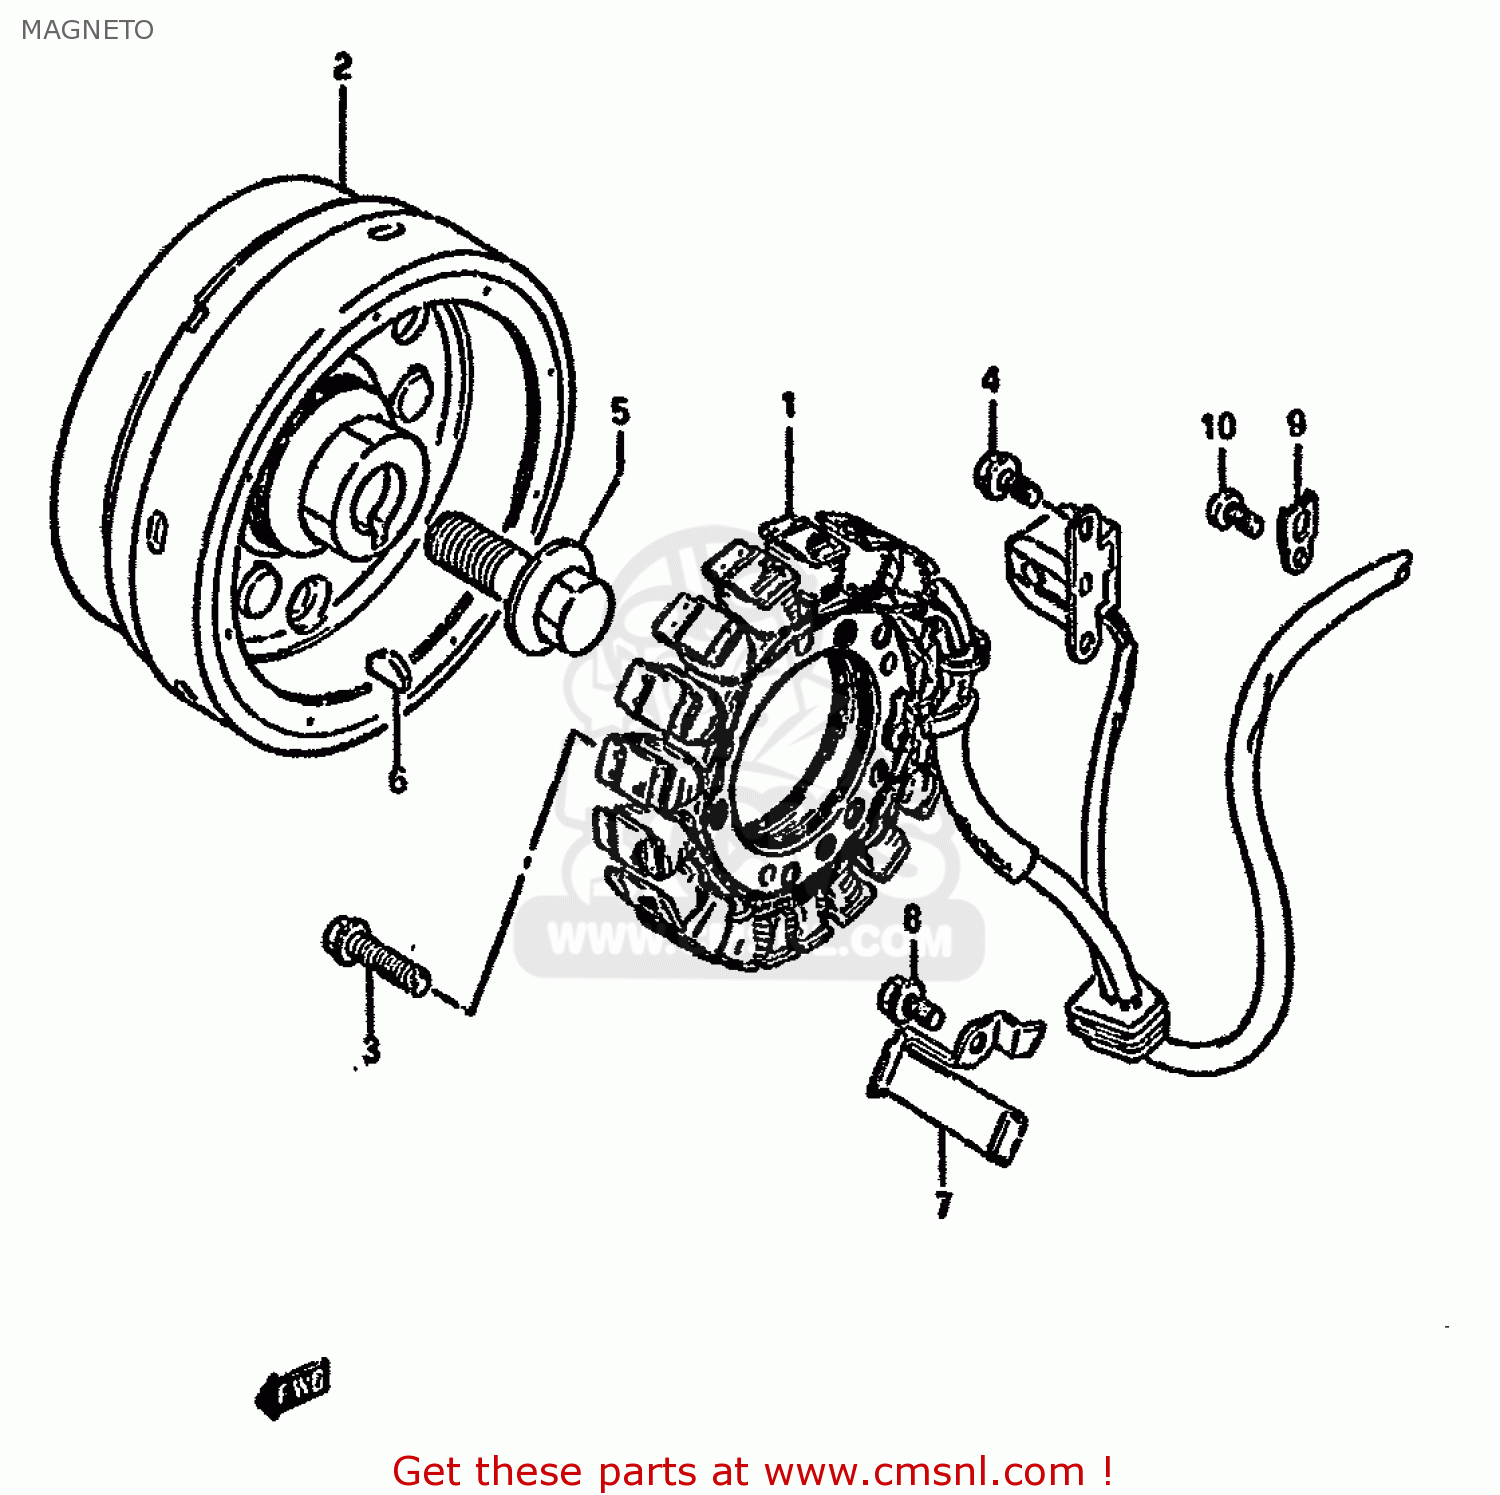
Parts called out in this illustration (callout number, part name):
1	STATOR ASSEMBLY
2	ROTOR,FLYWHEEL
3	BOLT
4	BOLT
5	BOLT(14X43)
6	KEY
7	CLAMP,MAGNETO LEAD WIRE NO.1
8	BOLT
9	CLAMP,GENERATOR LEAD WIRE
10	SCREW
